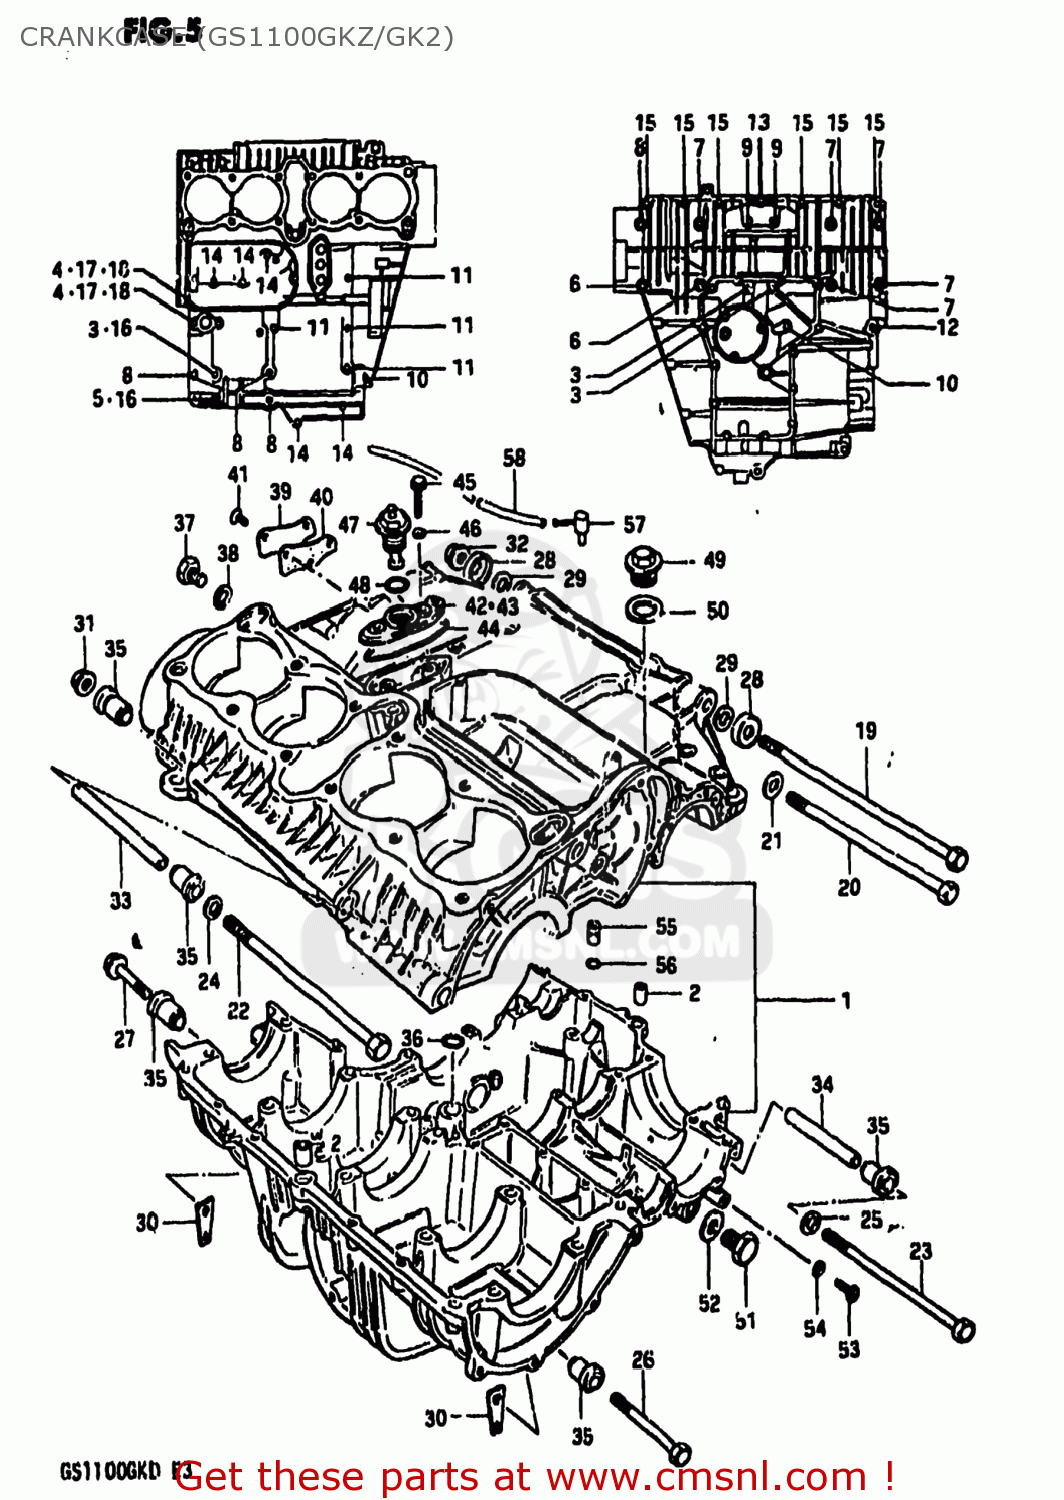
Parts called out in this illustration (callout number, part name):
1	CRANKCASE SET
2	PIN
3	BOLT
4	BOLT
5	BOLT
6	BOLT
7	BOLT 8X90
8	BOLT 8X65
9	BOLT
10	BOLT (6X90)
11	BOLT (6X75)
12	BOLT
13	BOLT ,6X50
14	BOLT,UNDER
15	BOLT 6X35
16	NUT
17	NUT
18	GASKET 8.2X14X1 (NAS)
19	BOLT
20	BOLT
21	WASHER
22	BOLT 10X250
23	BOLT
24	WASHER
25	WASHER
26	BOLT
27	BOLT 10X55
28	WASHER
29	WASHER(10.5X20X3.2)
30	NUT
31	NUT
32	NUT 10MM
33	SPACER
34	SPACER
35	BUSH
36	O RING(D:3.2,ID:12.9)
37	PLUG (14X12)
38	GASKET(14X19.2X2) (NAS)
39	CAP,OIL GALLERY
40	GASKET,OIL GALLERY (MCA)
41	SCREW
42	HOUSING,OIL PRESSURE SWITCH
43	HOUSING,OIL PRESSURE SWITCH
44	O RING,PRESSURE SWITCH HOUSING
45	BOLT
46	GASKET (NAS)
47	SWITCH ASSEMBLY
48	O RING(D:1.9,ID:18.8)
49	PLUG
50	GASKET
51	PLUG
52	GASKET
53	SCREW(6X10)
54	GASKET (NAS)
55	UNION
56	O RING(D:1.05,ID:3.1)
57	BPLUG,BEVEL GEAR BREATHER
58	HOSE
